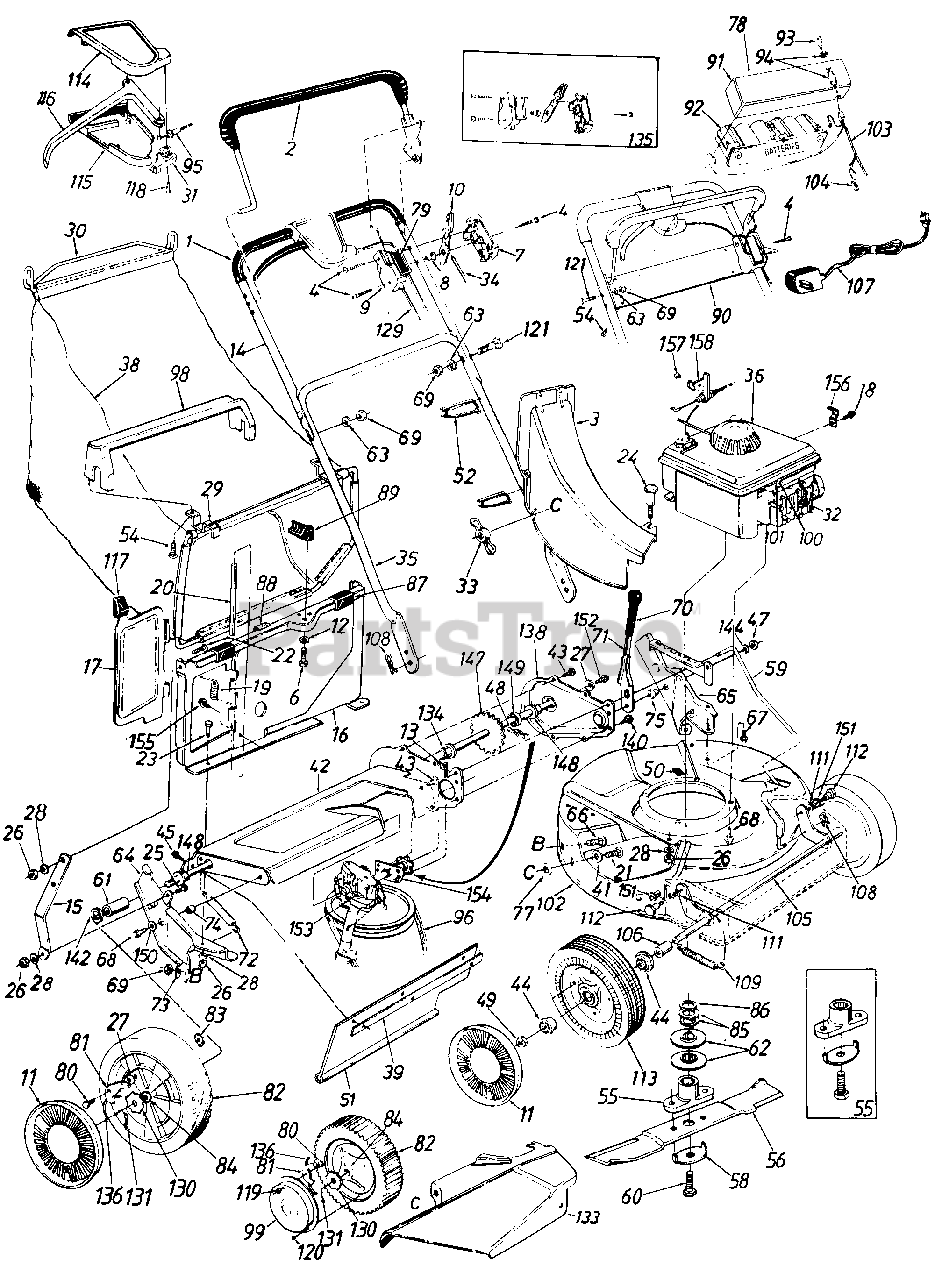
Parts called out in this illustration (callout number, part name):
1	Foam Grip
2	Control Handle Ass'y.-L.H.
3	Top Discharge Chute Ass'y.
4	Truss Mach. Scr. #12 x 1.50" Lg.
6	Hex Tap Scr. 1/4-20 x .75" Lg.
7	Control Panel Half
8	Control Disc Pin
9	Clutch Panel Half
10	Throttle Control Lever
11	Hub Cap
12	Spring Wash. .32" I.D.
13	Cotter Pin 3/32" Dia. x .75"*
14	Upper Handle-Chrome
15	Panel Support Brkt.
16	Top Catcher Panel Ass'y.
17	Top Discharge Door
18	Hex B-Tap Scr. #10 x .38"
19	Torsion Spring
20	Pivot Pin
21	Carriage Bolt 1/4-20 x .62"
22	Truss Mach. Scr. 1/4-20 x 3/4" Lg
23	Hex Bolt 1/4-20 x .50" Lg.
24	Shoulder Bolt .312 Dia. x .18 Lg.-Special
25	Hex Bolt 1/4-20 x .62" Lg.
26	Hex Nut 1/4-20 Thd.
27	Bell-Wash. 1/4" I.D.
28	L-Wash. 1/4" I.D.
29	Front Grass Catcher Frame
30	Grass Catcher Handle
31	S.P. Control Cover
32	Spark Plug Insulator
33	Wing Nut w/Washer
34	Throttle Control Wire 58"
35	Lower Handle-Chrome
36	Engine
38	21" Top Discharge Grass Bag-Black
39	Retaining Strip
41	Fl-Wash. .344" I.D. x .62"
42	Chain-Axle Ass'y.
43	Hex B-Tap Scr. 1/4" x .38" Lg.
44	Flange Ball Bearing 1/2" I.D.
45	Hex AB-Tap Scr. '/4 x .62"
47	Hex Patch L-Nut 3/8-24 Thd.
48	#48 Chain .500" Pitch x 30 Links
49	Hex L-Nut 1/2-20 Thd.
51	Rear Flap 3.75" x 17.30" Lg.
52	Cable Tie
54	Hex AB-Tap Scr. 1.0" Lg.
55	Blade Adapter Kit
56	21" Blade
58	Blade Bell-Wash. .44" I.D. x 2.38"
59	Height Adj. Rod 19.42" Lg.
60	Hex Bolt 7/16-20 x 1.5" Lg. (Grade 5)
61	Spacer .513" I.D. x .703" O.D. x .69" Lg.
62	Serrated Pulley Half
63	L-Wash. 5/16" I.D.*
64	R.H. Handle Wheel Brkt. Ass'y.
65	L.H. Handle Wheel Brkt. Ass'y.
66	Carriage Bolt 5/16-18 x .62"*
67	Hex Wash. Hd. B-Tap Scr. 5/1 6-1 8
68	Hex Wash. Hd. TT-Tap Scr. 3/8-1 6
69	Hex Nut 5/16-18 Thd.*
71	Height Adj. Lever
72	Extension Spring .50" O.D. x 3.80" Lg.
73	Bell-Wash. 5/16" I.D.
74	Spacer .385" I.D. x .502" O.D. x .270" Lg.
75	Shld. Spacer .500" Dia.
77	Bolt Retainer 1/4 x .50" O.D.
78	Instruction Label
79	Control Label
80	Shld. Scr. .342" Dia. x .268
81	Pawl
82	Wheel Ass'y. Comp.
83	Flat Weld Nut 1/4-20 Thd.
84	Bearing 1/2" I.D.
85	Wave Washer 1.005" I.D.
86	Serrated Washer 1.0" I.D.
87	Panel Clip
88	Foam Strip 1" Lg.
89	Grass Catcher Locking Knob
90	Lower Battery Tray
91	Upper Battery Tray
92	12 Volt Battery
93	Key
94	Key Switch
95	S.P. Cable x 50" Lg.
96	"V"-Belt
98	Bag Handle
99	Rear Hub Cap
100	Hex B-Tap Scr. #10 x .621'
101	Cable Clamp
104	Plug
105	Front Axle Ass'y.
106	Sleeve .526" I.D. x .690" O.D x.880" Lg.
107	Battery Charger
108	Intern. Cotter Pin 5/16" Dia.
109	Extension Spring .50" O.D. x 3.20" Lg.
111	Intern. L-Wash. 3/8 I.D.*
112	Shld. Bolt .575" Dia. x .42
113	Wheel Ass'y. Comp.
114	Self-Propelled Control Cover
115	Self-Propelled Control Cover
116	Control Lever
117	Door Grip
118	Fl-"C"-Sunk Hd. Tap Scr. #10 x .75" Lg.
119	Hex Ins. L-Nut 1/4-20 Thd.
120	Pan Hd. Tap Scr. #12 x .5" Lg.
121	Curved Carr. Bolt 5/16-18 x 1.38" Lg.
129	Control Cable 46" Lg.
130	Ratchet Wheel 1.62" O.D.
131	Cotter Pin 1/8" Dia. x 1.00" Lg.*
133	Side Chute Deflector Ass'y.
134	Hex Flange Bearing
135	Kit-Control Housing Comp.
136	Spring-Nylon
138	Chain Cover
140	Hex Wash. S-Tap Scr. 1/4-20 x.50" Lg.
142	Fl-Wash. .510" I.D. x 1.0"
144	Fl-Wash. .385" I.D. x .87"
147	Rear Shaft Ass'y. 21.94" Lg.
148	Hex Flange Bearing .506" I.D. Plastic
149	Fl-Wash. .531" I.D. x .930"
150	Fl-Wash. .531" I.D. x 1.25"
151	Flanged Nyliner Brg.
152	Hex Bolt 1/4-20 x .62" Lg. (Grade 5)
153	Transmission Comp.
154	Hex Bearing Cup
155	Hex B-Tap Scr. #10 x .38
156	Cable Clamp
157	Pop Rivet .156" Dia.
158	Cable Bracket
